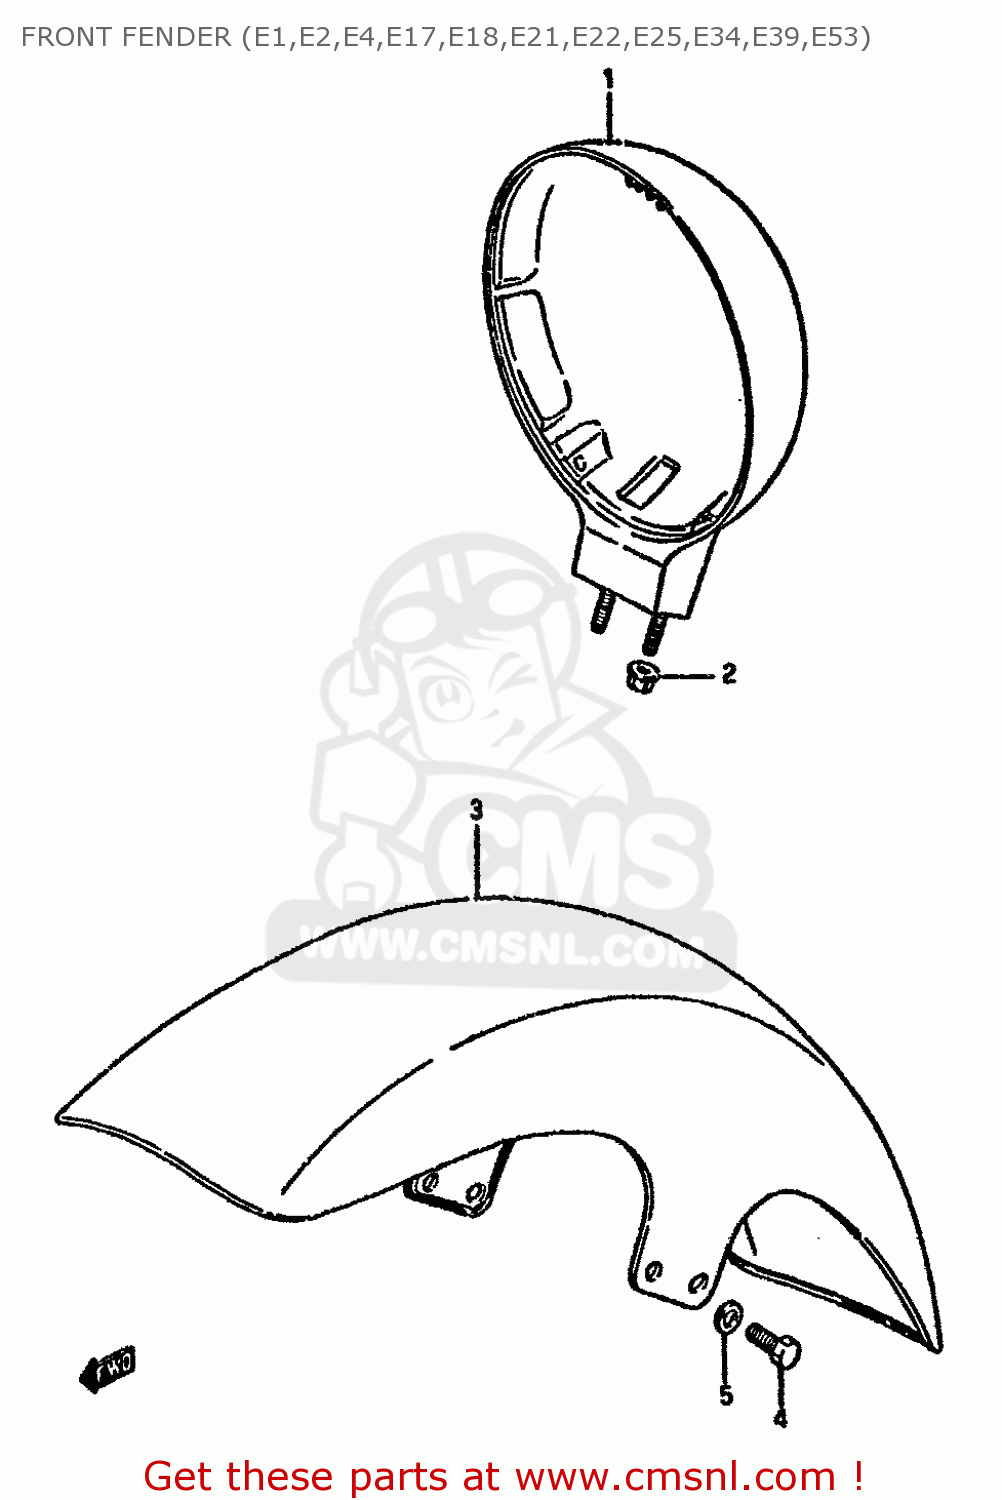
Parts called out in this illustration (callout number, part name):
1	HOUSING,HEADLAMP
2	NUT
3	FENDER,FRONT
4	BOLT
5	WASHER,LOCK
